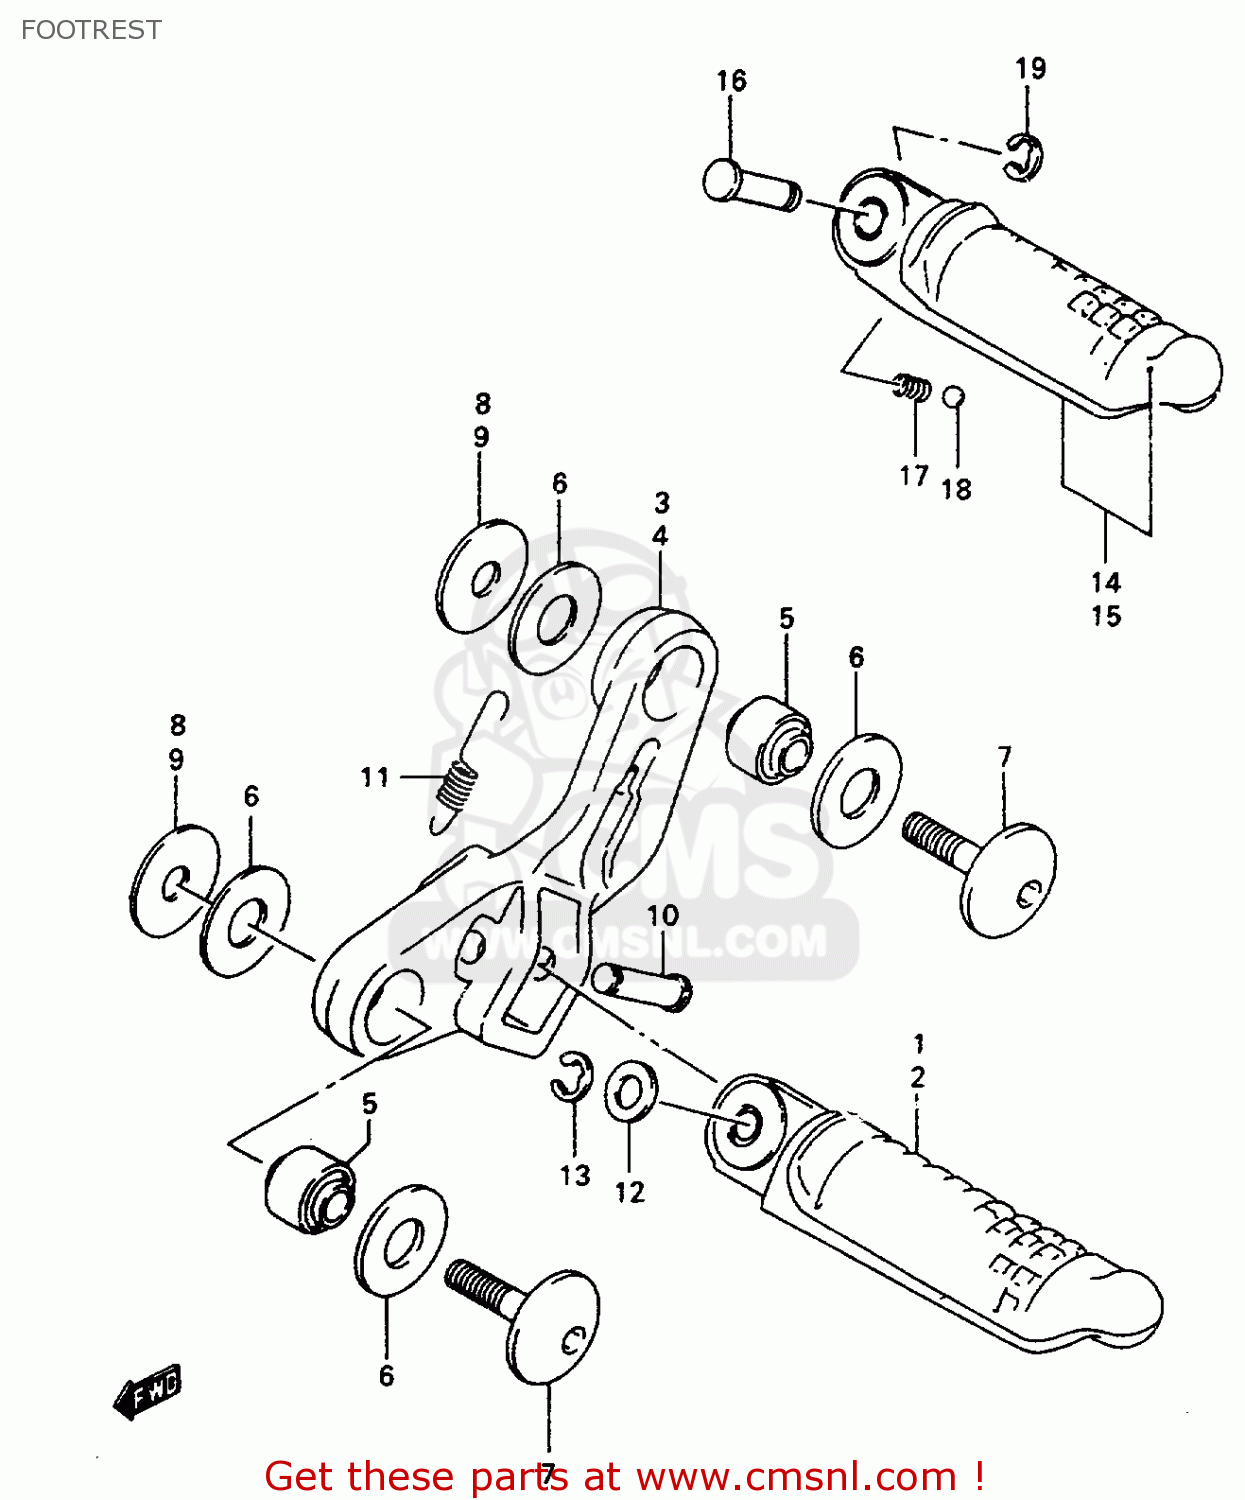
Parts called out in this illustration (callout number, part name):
1	BAR,FRONT FOOTREST,RIGHT
2	BAR,FRONT FOOTREST,LEFT
3	HOLDER,FR FOOTREST,R
4	HOLDER,FR FOOTREST,L
5	BUSH(8.4X20X18)
6	WASHER(12.5X30X2)
7	BOLT(8X33)
8	WASHER (8.5X30X2.3)
9	WASHER(8.5X30X2.3)
10	PIN(8X33.2)
11	SPRING
12	WASHER
13	E.RING
14	BAR,PILLION FOOTREST,RIGHT
15	BAR,PILLION FOOTREST,LEFT
16	PIN
17	SPRING
18	BALL
19	E.RING
